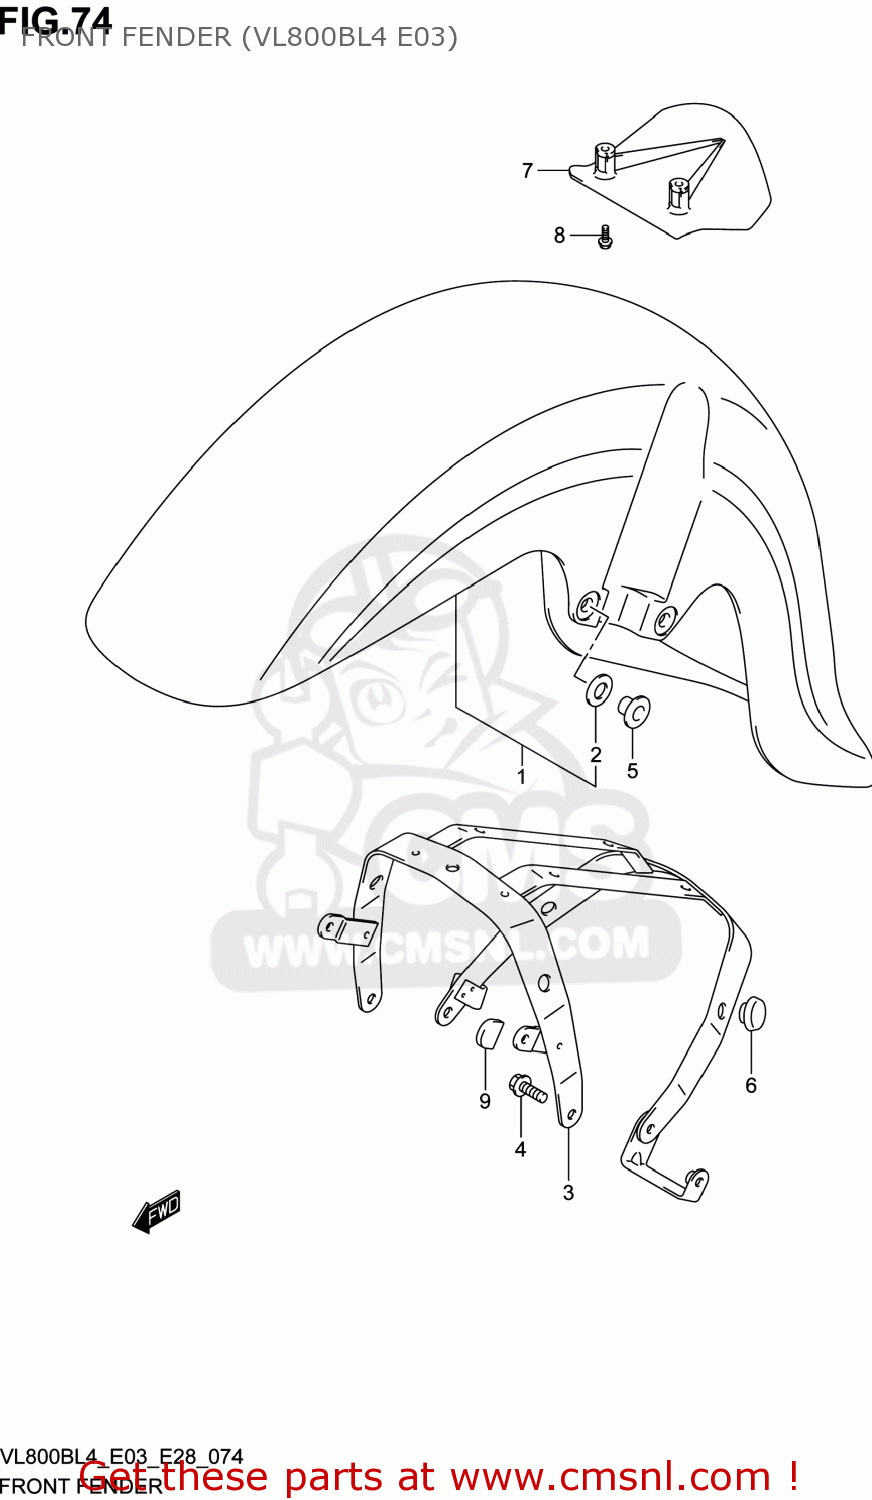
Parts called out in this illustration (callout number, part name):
1	FENDER,FR
2	CUSHION,FR FENDER
3	BRACE,FR FENDER
4	BOLT
5	WASHER,FR FENDER
6	CUSHION
7	WING,FR
8	BOLT(6X16)
9	CUSHION
